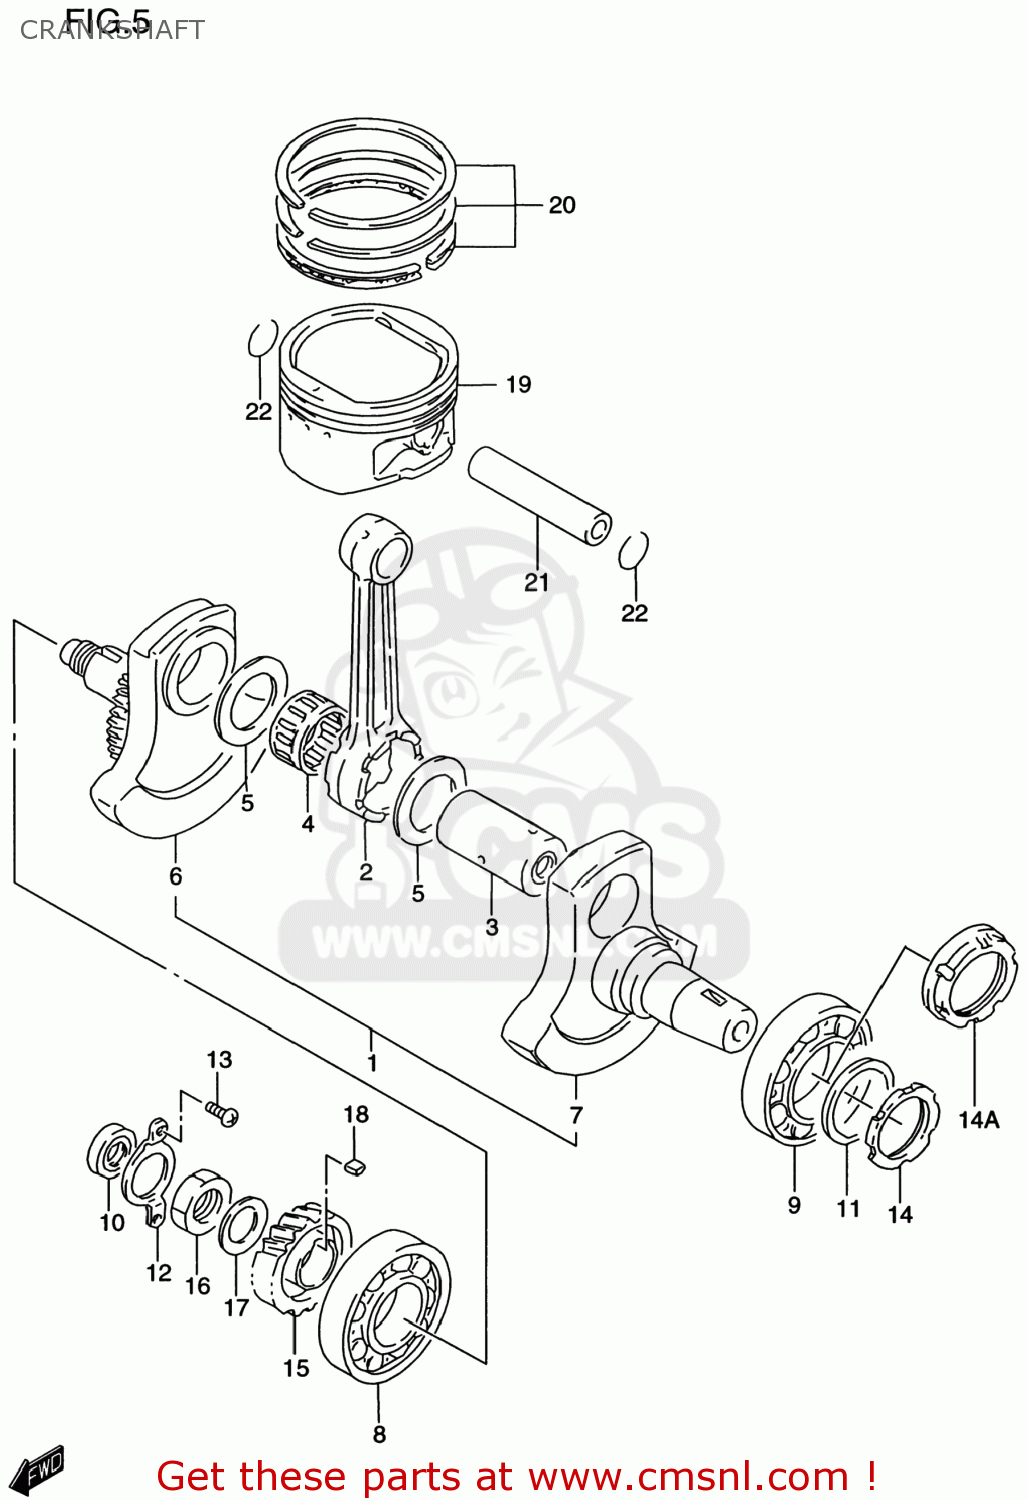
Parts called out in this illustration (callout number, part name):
1	CRANKSHAFT SET
2	CONNECTING ROD
3	PIN,CRANK
4	BEARING(37X47X25)
5	WASHER(37X55X1)
6	CRANKSHAFT SET,R
7	CRANKSHAFT,L
8	BEARING(40X80X18)
9	BEARING(45X85X19)
10	SEAL,OIL(16X30X6)
11	SPACER (40X54X5.5)
12	RETAINER,CRANKSHAFT BEARING,R
13	SCREW
14	NUT,BAL DRIVE SPRKT
14A	NUT,CRANKSHAFT BRG,L
15	GEAR,PRIMARY DRIVE(NT:28)
16	NUT (20MM)
17	WASHER
18	KEY
19	PISTON (100.00MM)
20	RING SET,PISTON
21	PIN,PISTON
22	CIRCLIP
